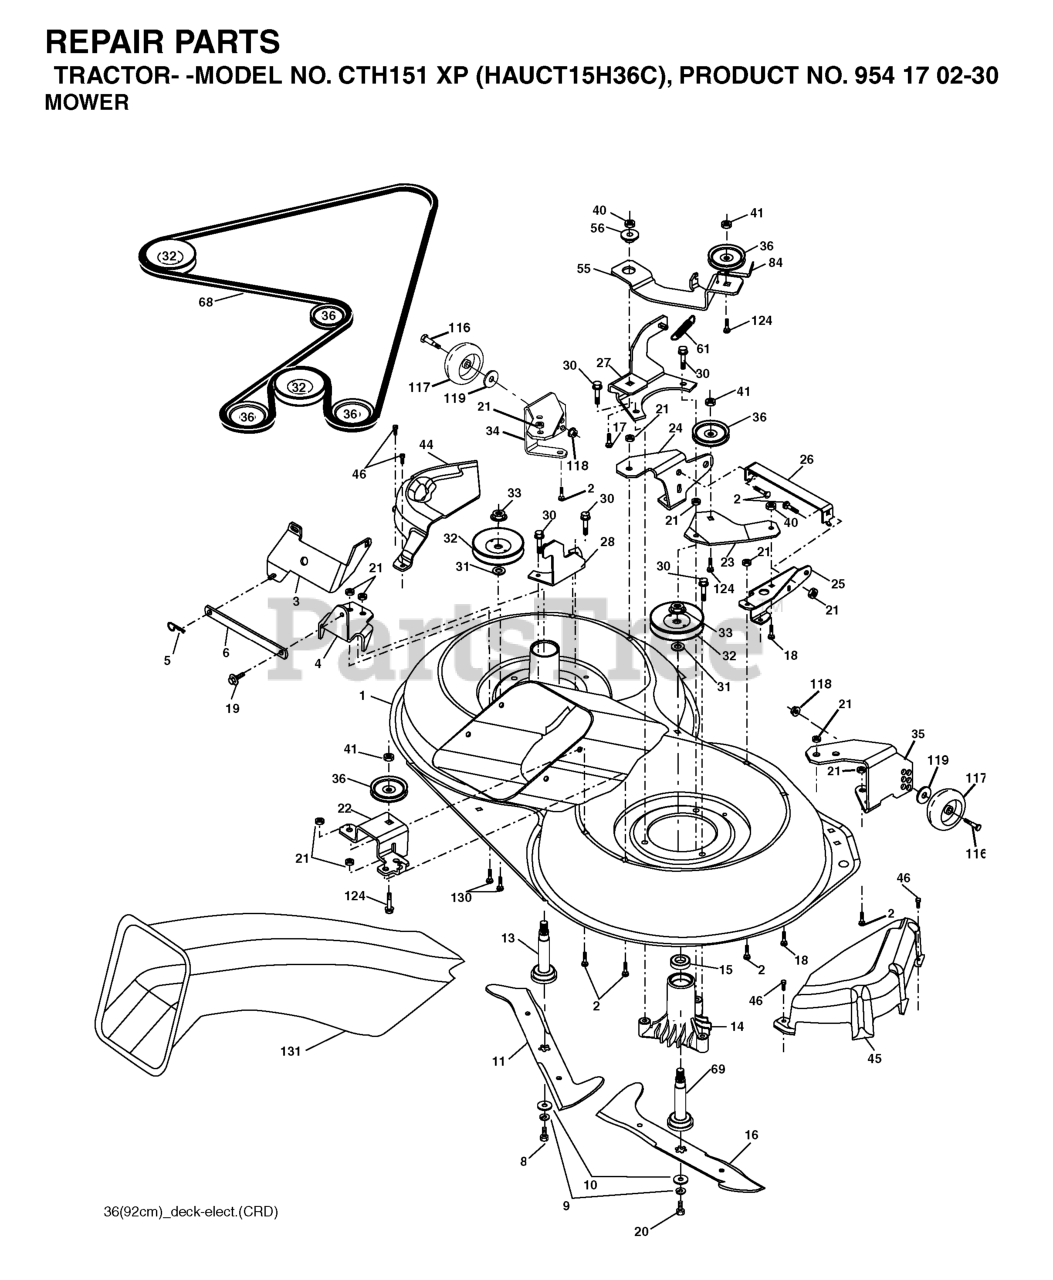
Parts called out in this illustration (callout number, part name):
1	MOWER HOUSING, DECK
2	RP BOLT 5/16-18 X3/4 ZN/YEL GR
5	RETAINER-SPRNG RB
6	BAR.SWAY.92.CRD
8	BOLT.3/8-24X1.25 GR8
9	LOCKWASHER
10	WASHER.BLADE
13	SHAFT ASM VENT
14	HOUSING.MANDREL.VENTED (MACHD)
17	BOLT.3/8-14X1.25
19	BOLT SHD 5/16-18
20	BOLT.3/8-24X1.25GR8. LHTHRD
21	LOCKNUT
26	BRACE.SUPT.SUSP.FRT.CRD
30	SCREW, WASHER HEAD
31	WASHER.SPACER.MANDREL
32	PULLEY, MANDREL
33	NUT, FLG TOPLOCK 9/16"
36	PULLEY.IDLER.4.25
41	NUT LOCK FLG 3/8-16 UNC
45	COVER.MANDREL.RH.CRD
46	SCREW.1/4-20X5/8
56	SPACER.RETAINER.MOWER
61	SPRING.TENSION.BELT
68	HEX-BELT
69	SHAFT.ASM.W/LWR.BRG.RH.THREAD
84	KEEPER, BELT IDLER
116	SHOULDER BOLT
117	WHEEL GAGE DONUT
118	LOCKNUT
119	WASHER.5/16.FLAT.STE.STD.
124	BOLT.3/8-16X1.50
130	BOLT.CARR.SQNK.5/16-18UNC.X3/4
131	CHUTE BAGGER
